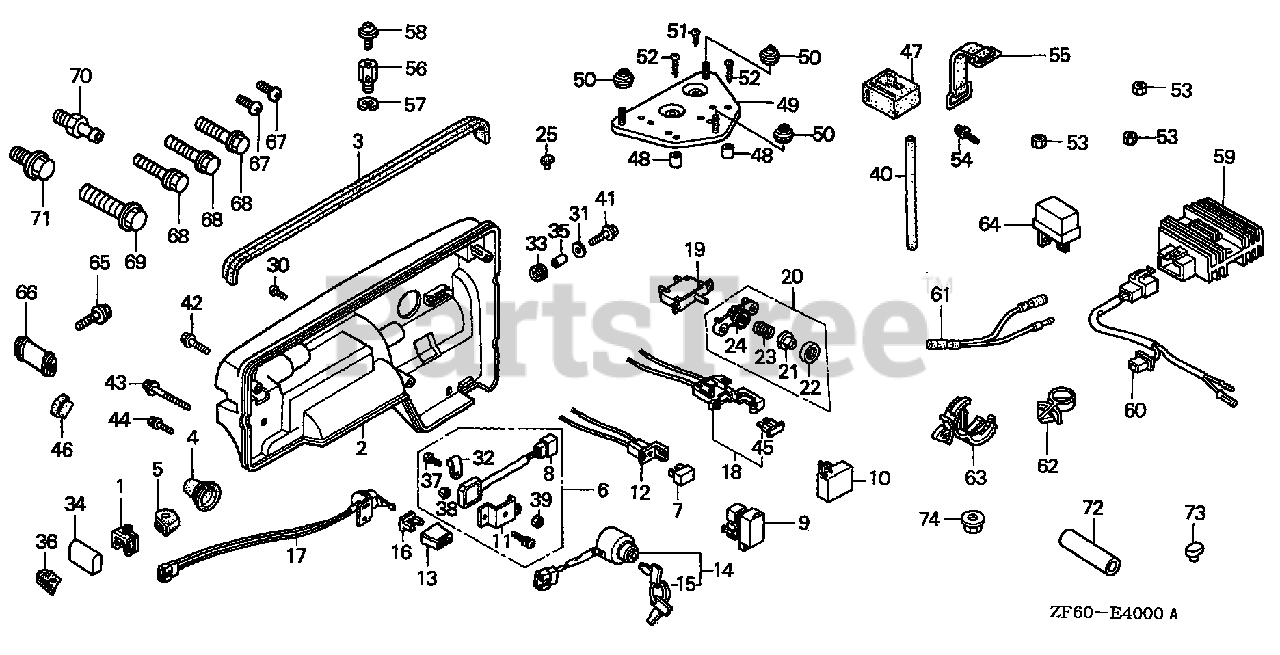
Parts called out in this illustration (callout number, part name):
65	BOLT, FLANGE (6X12) (CT200)
68	BOLT, FLANGE (6X20)
74	NUT, FLANGE (6MM)
